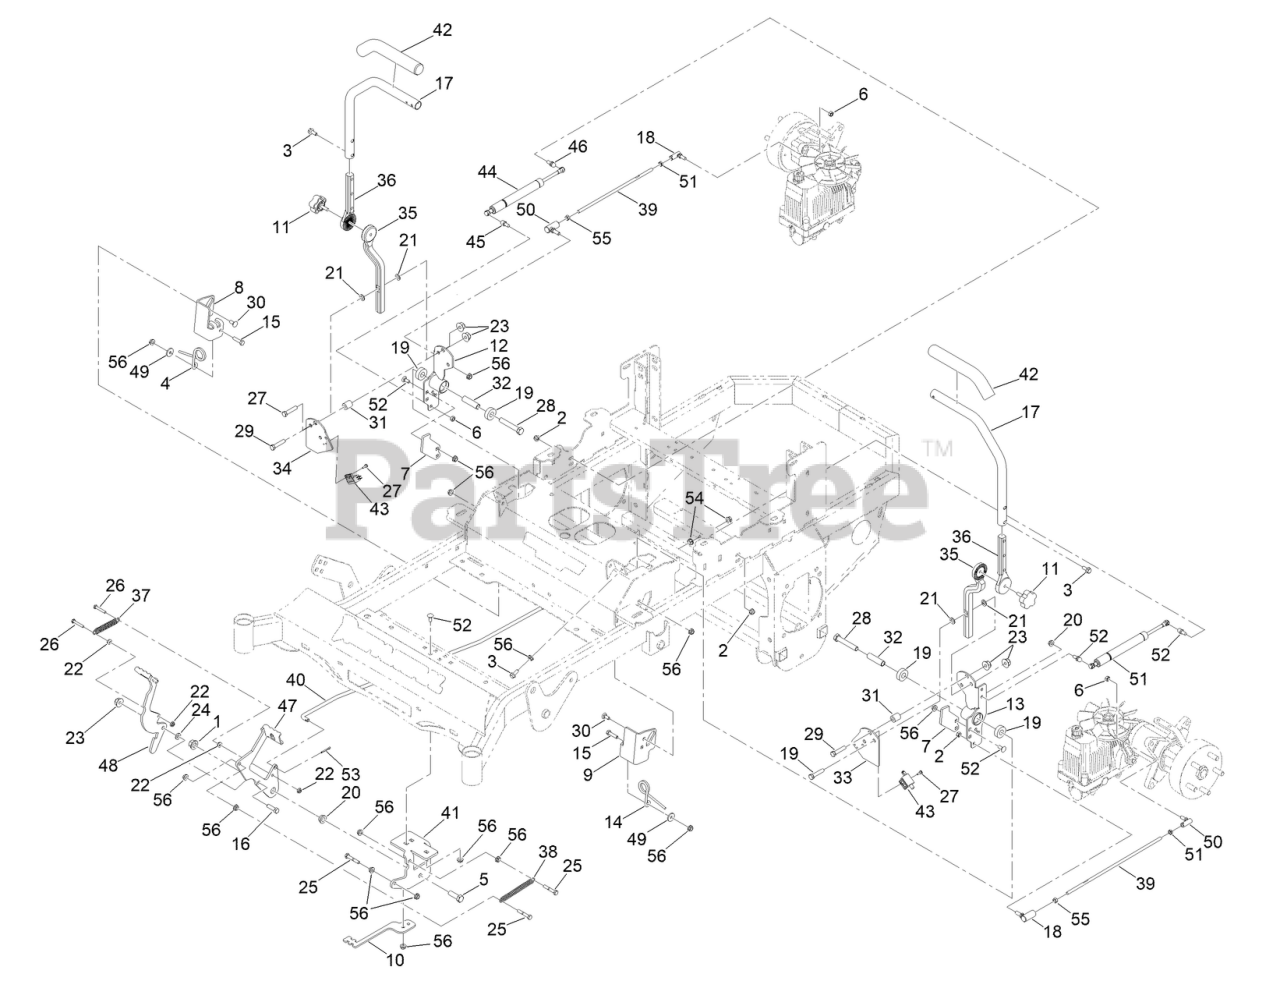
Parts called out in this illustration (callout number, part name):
1	NUT-LOCK
2	NUT-HF, NI
3	SCREW-HHF
4	SPRING-TORSION
5	SCREW-HH
6	5/16-24 NYL INS L/N GR.8 ZC/YEL
7	REVERSE DETENT KICK PLATE PAINTED BLACK
8	REV DENTENT SPRING BASE (RH)
9	REV DENTENT SPRING BASE (LH)
10	FAIR-RITE BRACKET PAINTED
11	5/16-18 X 1 SL 5-LOBE MALE ST KNOB 1.90
12	RT DRIVE ARM BRKT ASSY PAINTED BLACK
13	MWR LT DRIVE ARM BRKT ASSY
14	SPRING- LT REVERSE DETENT
15	SCREW-HH
16	SCREW-HH
17	MOWER DRIVE HANDLE TUBE ABC
18	CONTROL ARM ROD END LT
19	5/8IN ID X 1-3/8IN OD X 7/16IN THK BRG
20	1/2IN ID X 3/4IN OD X 3/8IN FLANGE BUSH
21	3/8 X 3/4 BRONZE WASHER
22	1/4-20 HEX FLANGE NUT
23	3/8-16 NYLON INSERT FLANGE L/NUT YZ
24	3/8 ID X 3/4 OD X .125 THK BRONZE WASHER
26	1/4-20 X 1-1/4 HEX C/S GR 2 ZINC
27	8-32 X 1/2 IND. HWH SLOT TYPE F TCS ZINC
28	1/2-13 X 3 HEX C/S GR 5 ZINC W/LOCTITE
29	3/8-16 X 1-3/4 HEX C/S GR 2 ZINC
30	5/16-18 X 1 CARRIAGE BOLT GR 8 YZ
31	MWR DRIVE ARM SPACER
32	MWR DRIVE ARM HUB / DECK LIFT ARM SPACER
33	MWR LT CTRL ARM LIMIT SWTCH PLATE BLACK
34	MWR RT CTRL ARM LIMIT SWTCH PLATE BLACK
35	ADJUSTABLE LWR DRIVE ARM
36	ADJUSTABLE UPP DRIVE ARM
37	MWR BRAKE PEDAL RELEASE SPRING
38	2020 MWR BRAKE PEDAL TENSION SPRING
39	TRANS DRIVE ARM LINKAGE STANDARD TRANS
40	MWR BRAKE LINKAGE
41	MWR FRAME BRAKE MTG BRKT BLACK
42	CONTROL ARM HANDLE GRIP
43	NO PLUNGER LIMIT SWITCH
44	CONTROL ARM DAMPER
45	5/16-18X1.286 DAMPER BALL STUD (.562 TL)
46	5/16-18X1.286 DAMPER BALL STUD (.562 TL)
47	MWR BRAKE LOCK LEVER ASSY BLACK
48	MWR BRAKE UNLOCK LEVER ASSY BLACK
49	STRIKER POST FENDER WASHER
50	BALLJOINT-RH (W/GROMMET)
51	NUT-JAM
52	BOLT-CARR
53	PIN-COTTER
54	3/8-16 HEX FLANGE NUT W/SERR ZINC YELLOW
